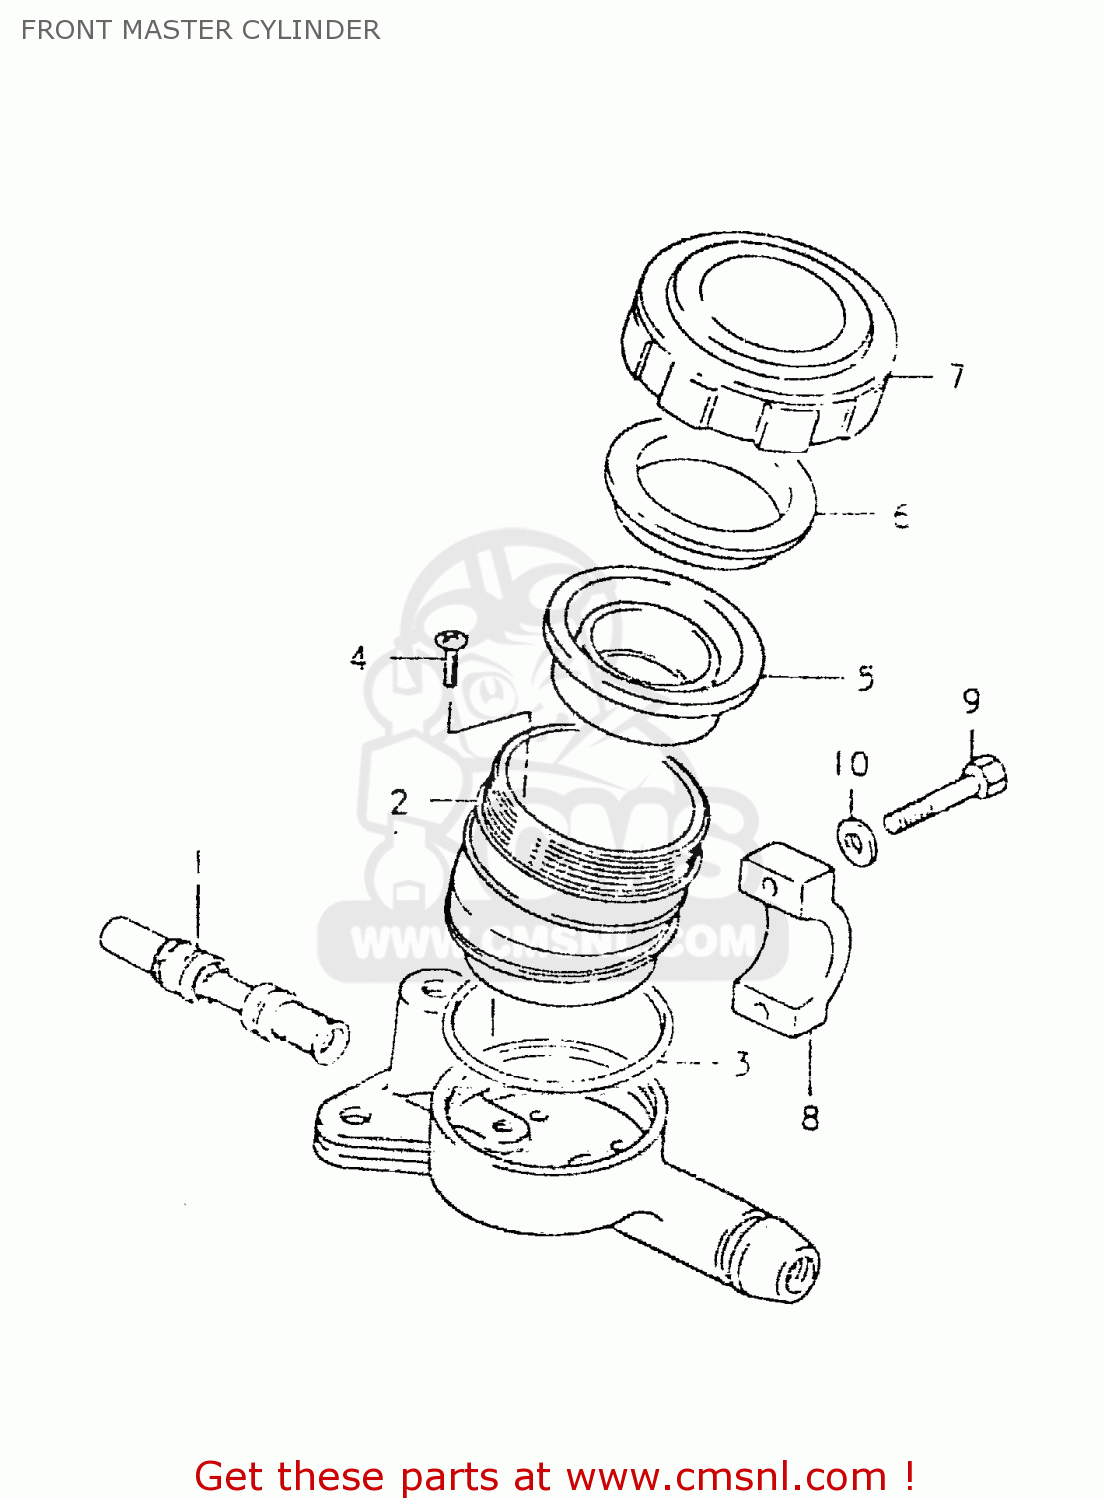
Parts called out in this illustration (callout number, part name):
1	PISTON & CUP SET
2	RESERVOIR
3	O RING
4	SCREW,MASTER CYLINDER
5	DIAPHRAGM
6	PLATE
7	CAP
8	HOLDER,MASTER CYLINDER
9	BOLT
10	WASHER
